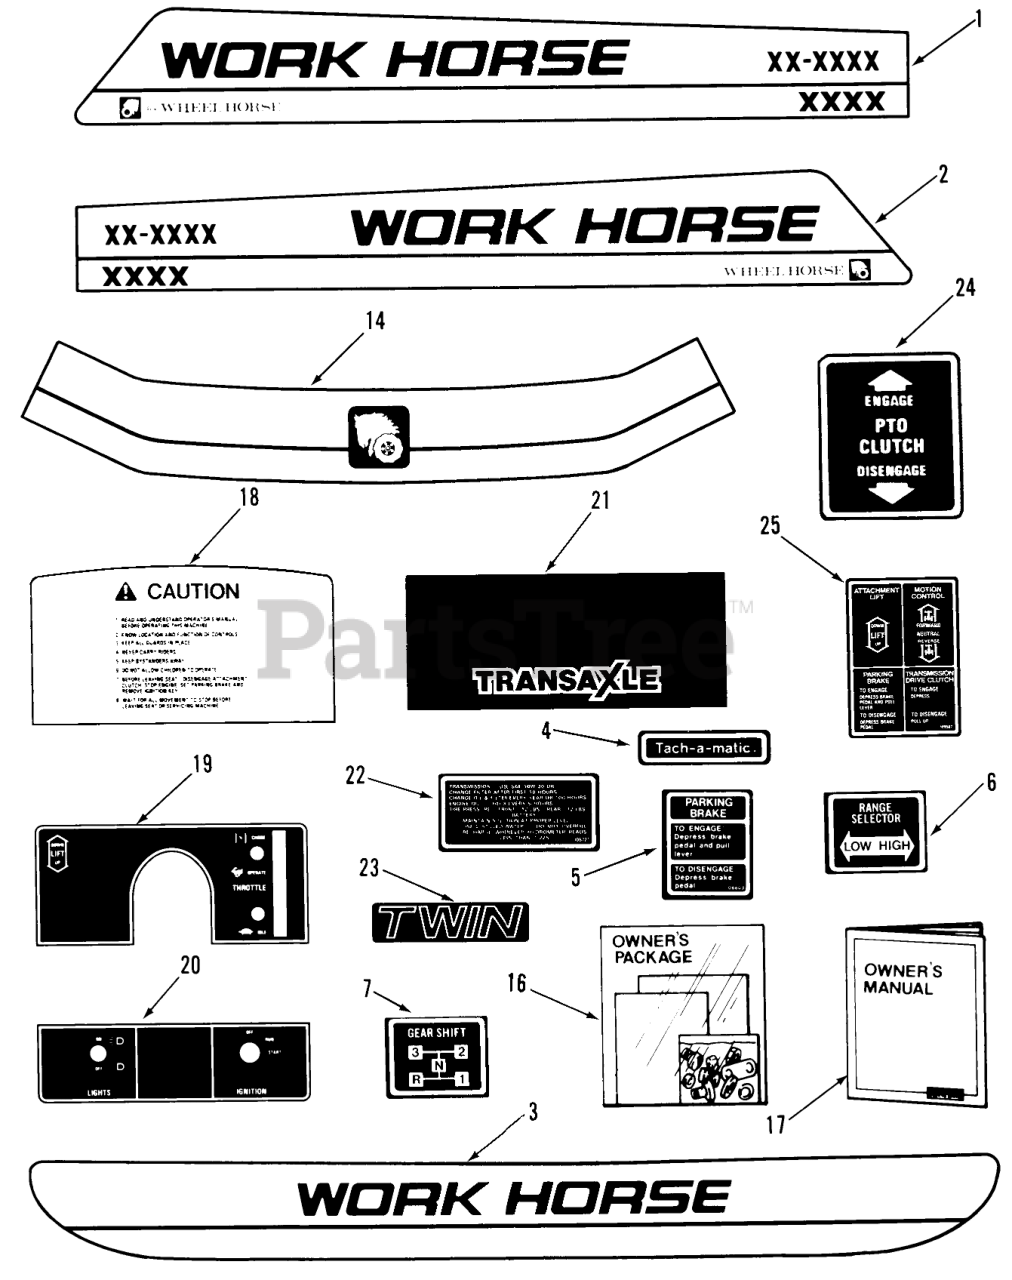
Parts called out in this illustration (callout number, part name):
1	DECAL HOOD LH
1	Decal LH GT-1642 8-Speed
2	DECAL HOOD RH
2	Decal RH GT-1642 8-Speed
3	Decal Rear
4	DECAL-TACHAMATIC
5	DECAL-PARKING BRAKE
6	DECAL HI-LO
7	DECAL-SHIFT
14	DECAL - HOOD FRONT
16	Loose Parts Package GT-1642, GT-1848 Only
16	Loose Parts Package GT-1142 Only
17	Owner-s Manual-Tractor
17	Mower Operator-s Manual
18	DECAL - CAUTION
19	Decal-Dash GT-1800 Only
19	DECAL - LOWER DASH
20	DECAL-BACK PLATE-SWI
21	DECAL - TRANSAXLE
22	Decal-Maintenance
23	Decal-Engine LT-1600 Only
24	DECAL-PTO CLUTCH
25	Decal-Speed Control, Lift, Parking Brake GT-1800 Only
